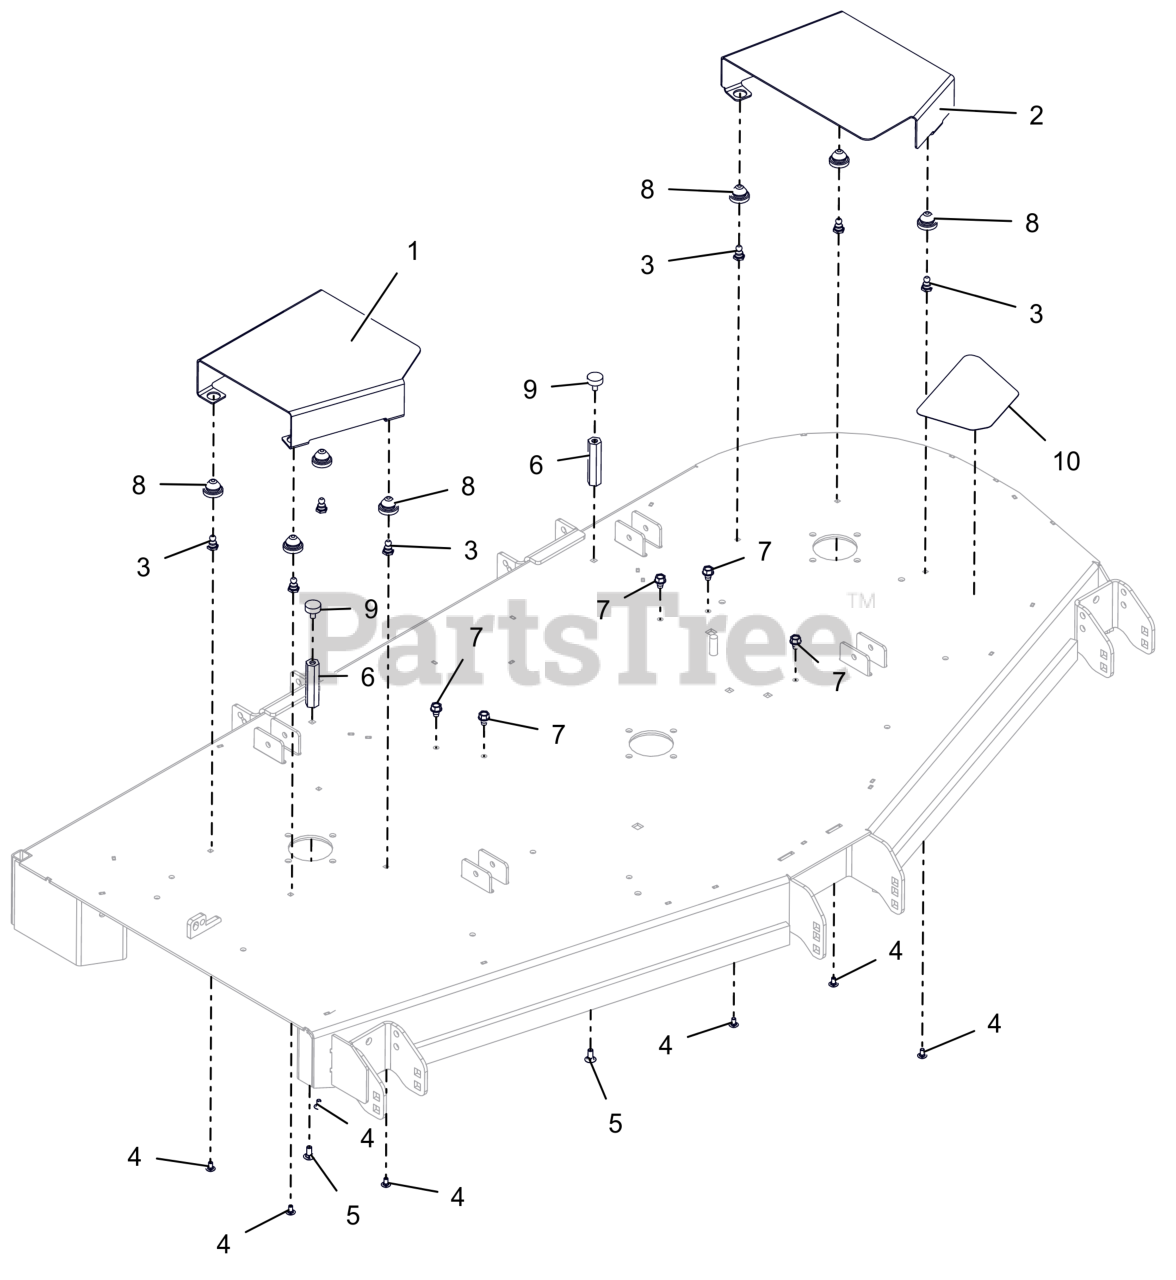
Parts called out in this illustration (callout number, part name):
1	GUARD, 72" DECK RH SPINDLE PULLEY
2	GUARD, 72" DECK LH SPINDLE PULLEY (RED)
3	STUD, BALL FEMALE .250-20 THREAD
4	BLT, RHSSN.25-20X.500 G5 ZCC
5	BTL,RHSN .313-18 X 0.75 G5 ZCC LT
6	NUT, COUPLING .312-18 X 3.250
7	SCR,TAP .375-16X.50 HWH TR ZCC
8	COUPLING, RUBBER PUSH-IN
9	BUMPER, RUBBER
10	GRIP, STEP ANTI SKID
